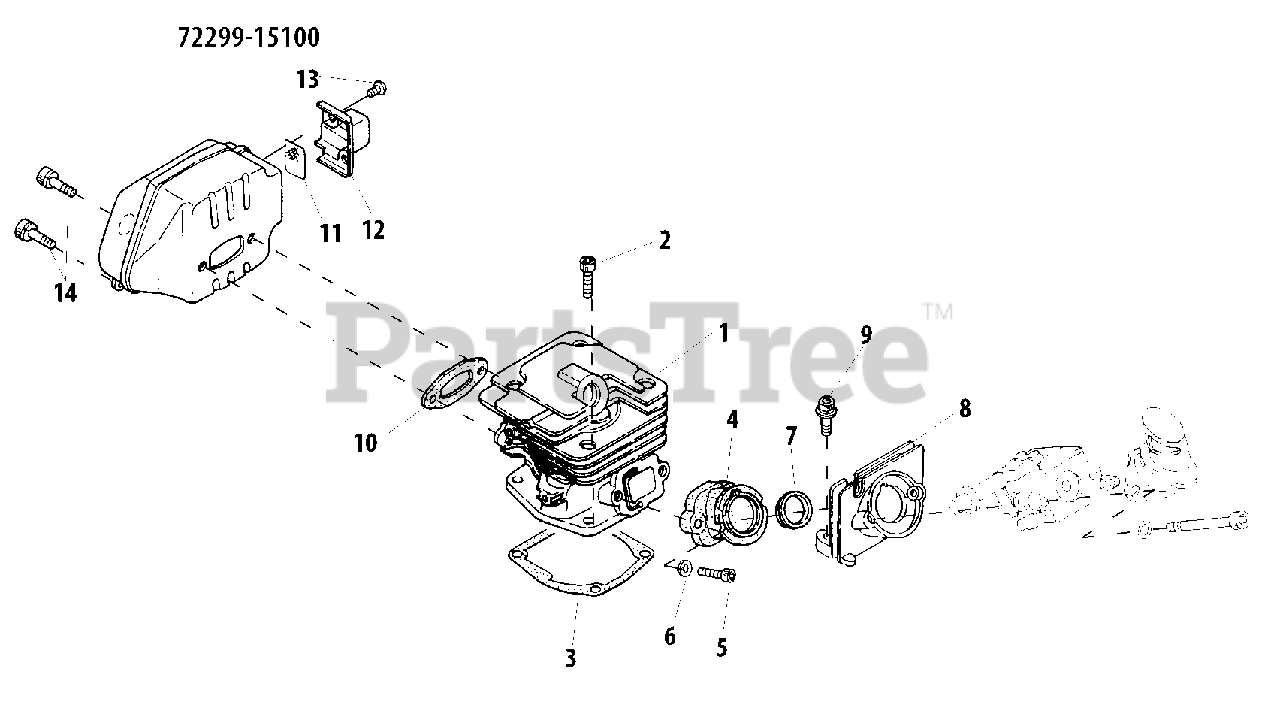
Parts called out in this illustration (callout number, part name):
1	CYLINDER
3	GASKET, CYLINDER
4	BOOT
5	SCREW - 4X12
6	WASHER - 4
7	SLEEVE
8	BRACKET
9	SCREW - 4X14
10	GASKET, EXHAUST
11	SCREEN, SPARK ARRESTOR
12	GUIDE, EXHAUST
13	SCREW - 4X6
14	SCREW - 5X16
72299-15100	MUFFLER ASSY
